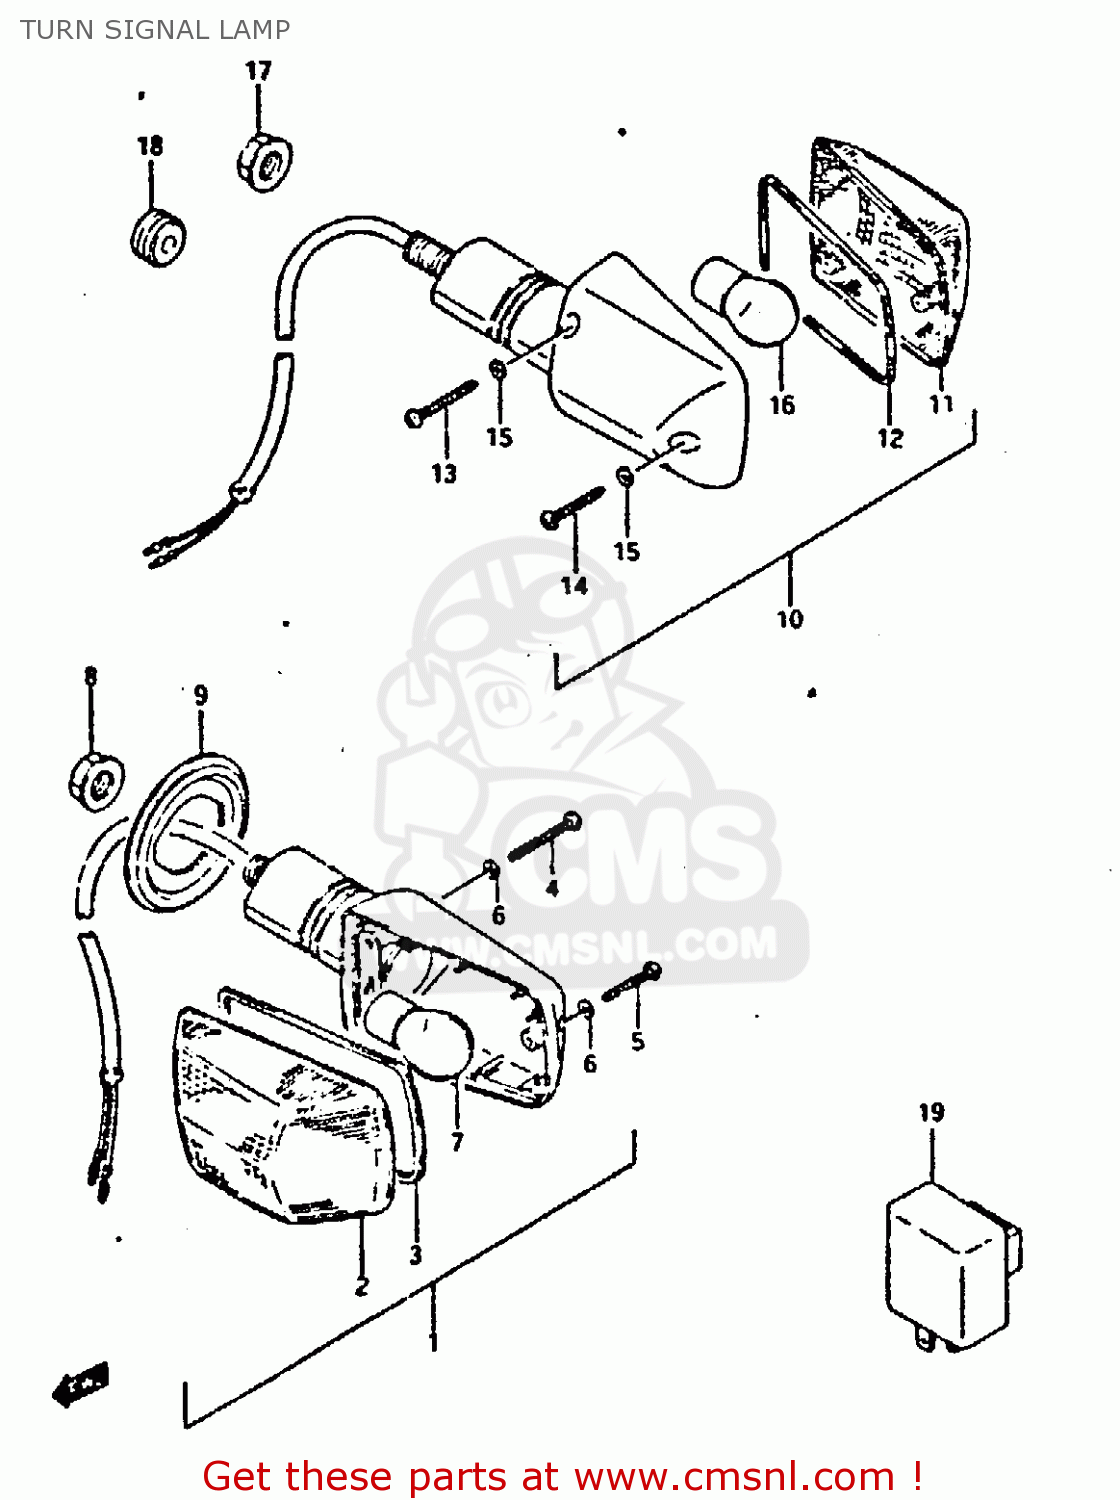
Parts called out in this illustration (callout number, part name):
1	LAMP ASSY,RR TURNSIGNAL
2	LENS
3	GASKET (NAS)
4	SCREW(3X30)
5	SCREW
6	GASKET (NAS)
7	BULB(12V23W,STANLEY,A4577A)
8	NUT
9	GROMMET
10	LAMP ASSY,RR TURNSIGNAL
11	LENS
12	GASKET (NAS)
13	SCREW(3X30)
14	SCREW
15	GASKET (NAS)
16	BULB(12V23W,STANLEY,A4577A)
17	NUT
18	GROMMET
19	RELAY ASSEMBLY,TURN SIGNAL
